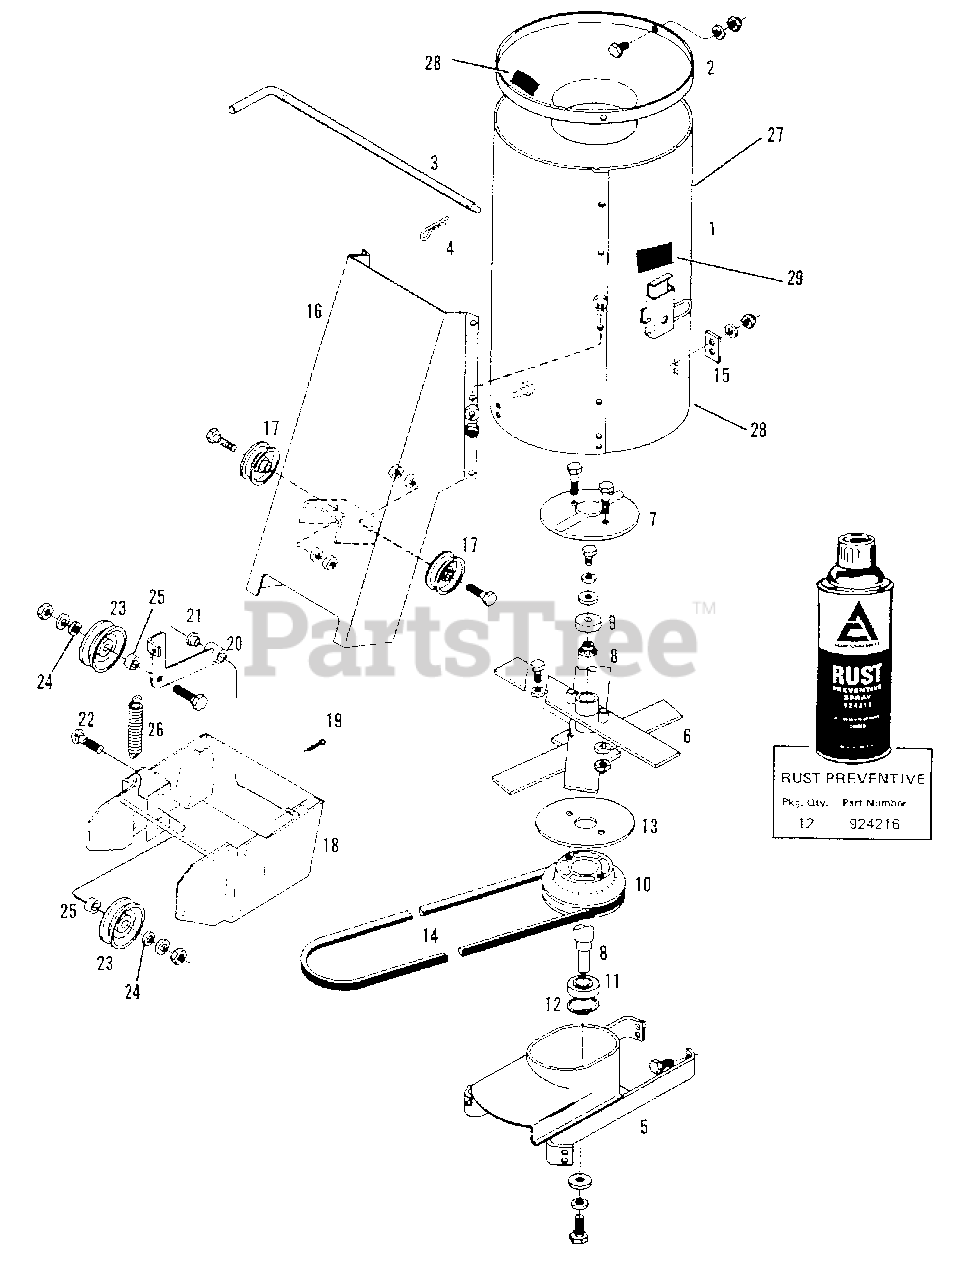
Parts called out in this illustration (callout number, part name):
1	TANK ASSEMBLY
1	CAPSCREW, 3/8NC x 7/8
1	LOCKWASHER, 3/8
1	NUT, Lock, 3/8NC
1	CAPSCREW, 3/8NC x 1
2	CAPSCREW, 3/8NC x 3/4
2	LOCKWASHER, 3/8
2	NUT, 3/8NC, Lock
3	ROD, Breaker
4	CLIP, Spring
5	SUPPORT ASSEMBLY, Blade
5	CAPSCREW, 3/8NC x 7/8
5	LOCKWASHER, 3/8
5	NUT, 3/8NC, Lock
6	BLADE & ADAPTER ASSEMBLY
6	CAPSCREW, 3/8NC x 1
6	LOCKWASHER, 3/8
6	NUT, 3/8NC, Lock
7	CAPSCREW, 3/8NC x 1-3/4
7	LOCKWASHER, 3/8
8	SHAFT, Main
8	CAPSCREW, 3/8NC x 3/4
8	LOCKWASHER, 3/8
8	WASHER
8	CAPSCREW, 1/2NC x 1-1/2
8	LOCKWASHER, 1/2
8	WASHER, 1/2
12	RING, Retaining
13	PLATE, Disc
15	WASHER, 2 Hole
16	CHANNEL ASSEMBLY, Mounting
17	PULLEY, Idler
17	CAPSCREW, 3/8NC x 1-3/4
17	LOCKWASHER, 3/8
17	NUT, Lock, 3/8
18	HANGER ASSEMBLY.
19	PIN, Cotter
20	ARM ASSEMBLY, Idler Pivot
21	BUSHINGS, Axle
22	BOLT, Carriage
23	PULLEY, Idler
23	CAPSCREW, 5/8NC x 2
23	LOCKWASHER, 5/8
23	NUT, 5/8NC
27	TRANSFER, Allis-Chalmers
28	TRANSFER, Caution
29	TRANSFER, Instruction
